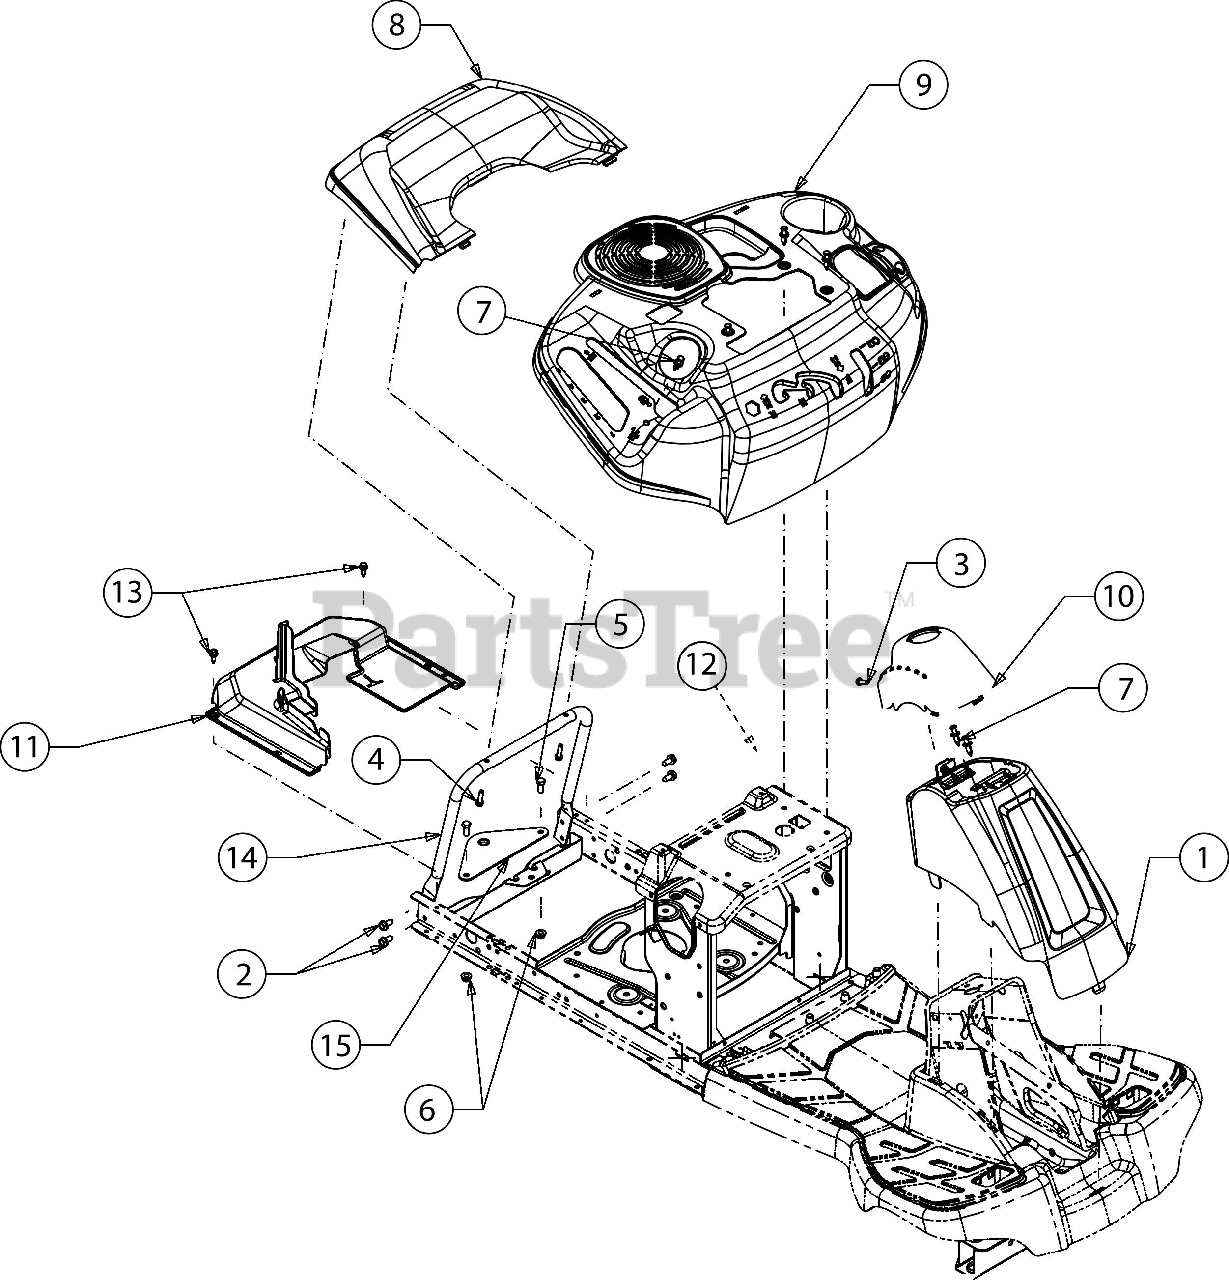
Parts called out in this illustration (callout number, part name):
1	COLUMN COVER ASSEMBLY (MTD RED)
2	SCREW 5/16-18 x .750
3	SCREW 1/4-20X.75
4	SCREW 1/4-15 x 1.00
5	SCREW 5/16-18 x .75 GR5
6	FLANGE LOCK NUT 5/16-18
7	PLASTIC RIVET
9	FENDER
10	COLUMN STEERING CAP
11	DRIVE OVER REAR
12	BUMPER .62 DIA x .50
13	SHOULDER SCREW
14	REAR SUPPORT TUBE
15	HITCH PLATE
